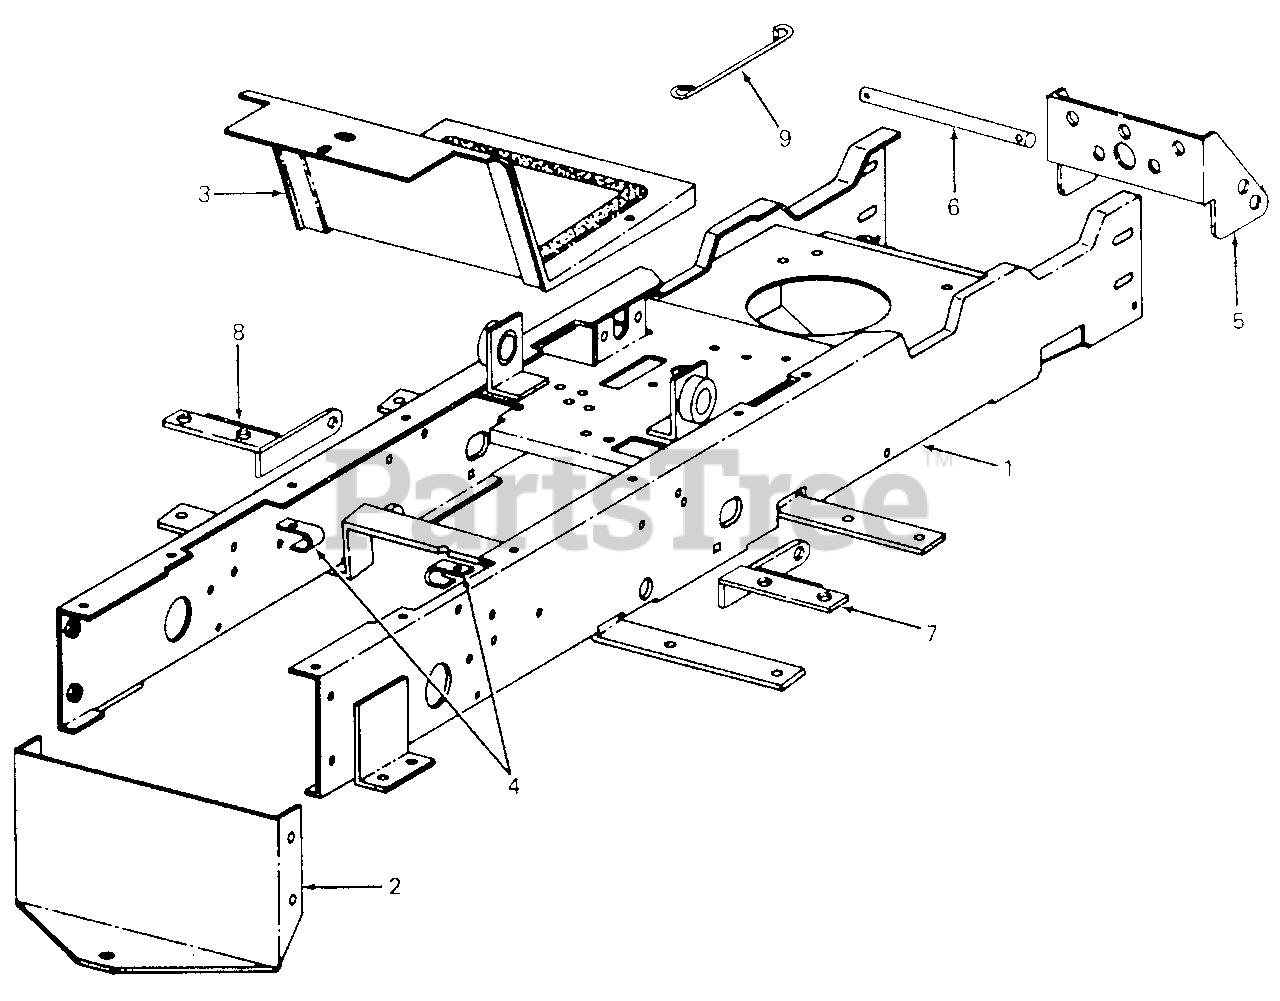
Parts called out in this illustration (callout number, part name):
3	Cover w/Graphic
4	Clip, Cable
5	Front Mower Support
6	Deck Support Rod
7	Rear Deck Bracket Assy RH
8	Rear Deck Bracket Assy LH
9	Link Retaining Rod
